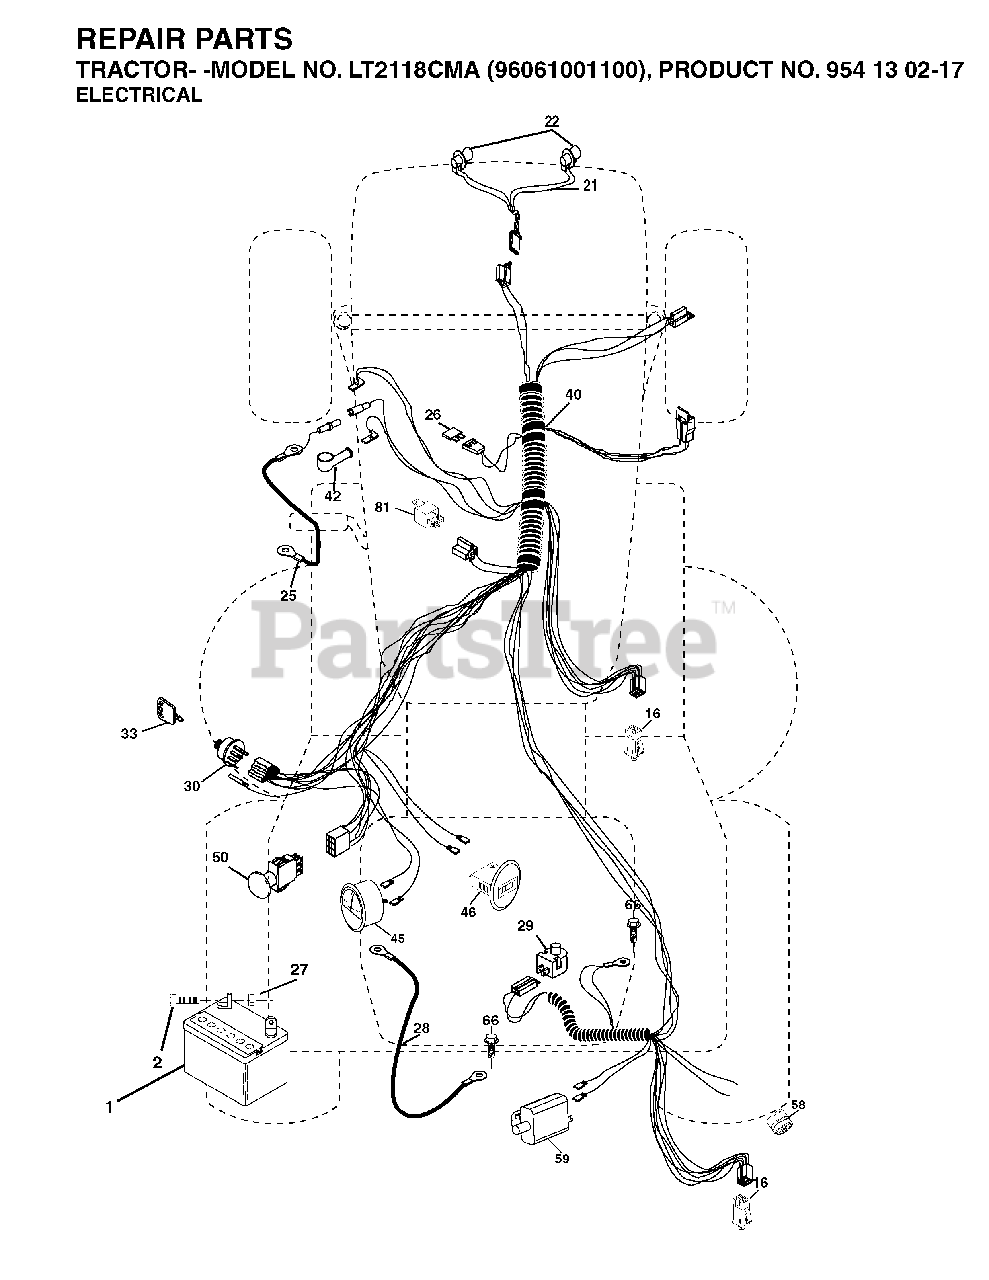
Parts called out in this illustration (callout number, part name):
1	BATTERY 12V .35 AMP
16	SWITCH INTERLOOK PUSH-IN
21	HARNESS.W/LIGHT SOCKET
22	LIGHTBULB
26	FUSE 20AMP
27	NUT
28	CABLE GROUND
29	SWITCH SEAT
30	IGNITION SWITCH
33	KEY MLD GEN DELTA
42	COVER.TERMINAL.RED
46	HOURMETER SNAP-IN
50	PTO SWITCH
58	BUZZER
79	BULB HOLDER ASM.
81	RELAY.ASSY.T
